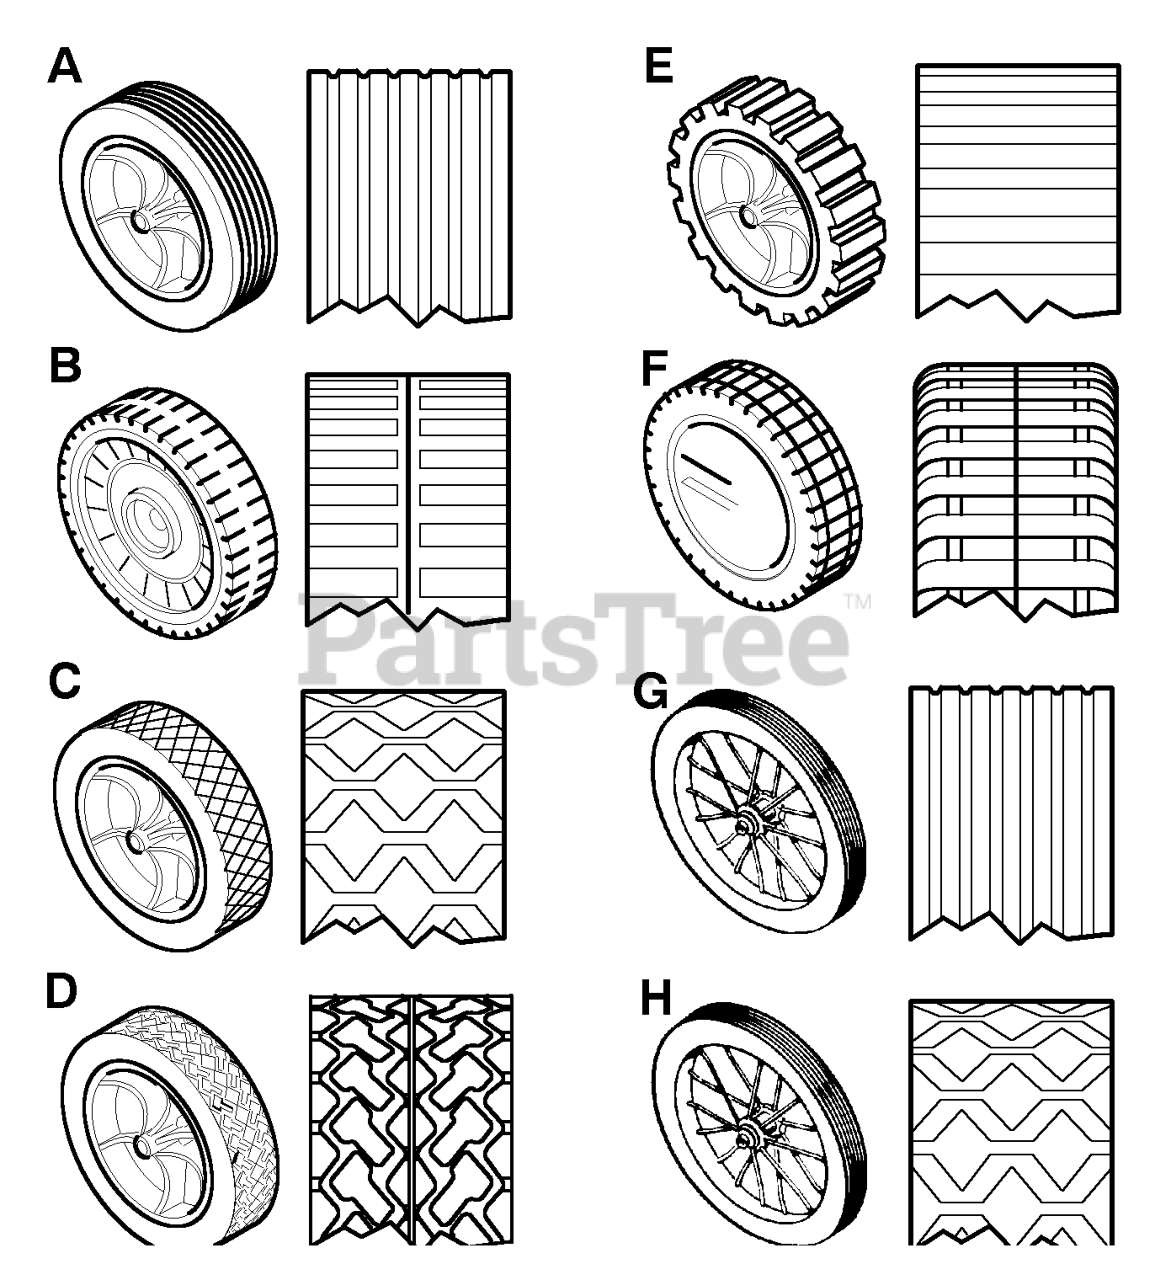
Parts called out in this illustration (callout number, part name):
C	6-inch Plastic, White
B	7-inch Plastic, White
C	7-inch Plastic, White
D	7-inch Plastic, White
B	7-inch Plastic, Gray
C	7-inch Plastic, Gray
A	WHEEL & TIRE ASSEMBLY, Light Gray, 8"
C	8-inch Plastic, White
D	WHEEL & TIRE ASSEMBLY, White, 8"
E	WHEEL & TIRE ASSEMBLY, White, 8"
F	WHEEL & TIRE ASSEMBLY, White, 8"
A	8-inch Plastic, Gray
D	8-inch Plastic, Gray
E	8-inch Plastic, Gray
F	8-inch Plastic, Gray
A	8-inch Metal, White
C	8-inch Metal, White
E	8-inch Metal, White
F	8-inch Ball Bearings, Gray
G	14-inch Spoke
G	16-inch Spoke
H	WHEEL & TIRE ASSEMBLY, 16" Spoke
